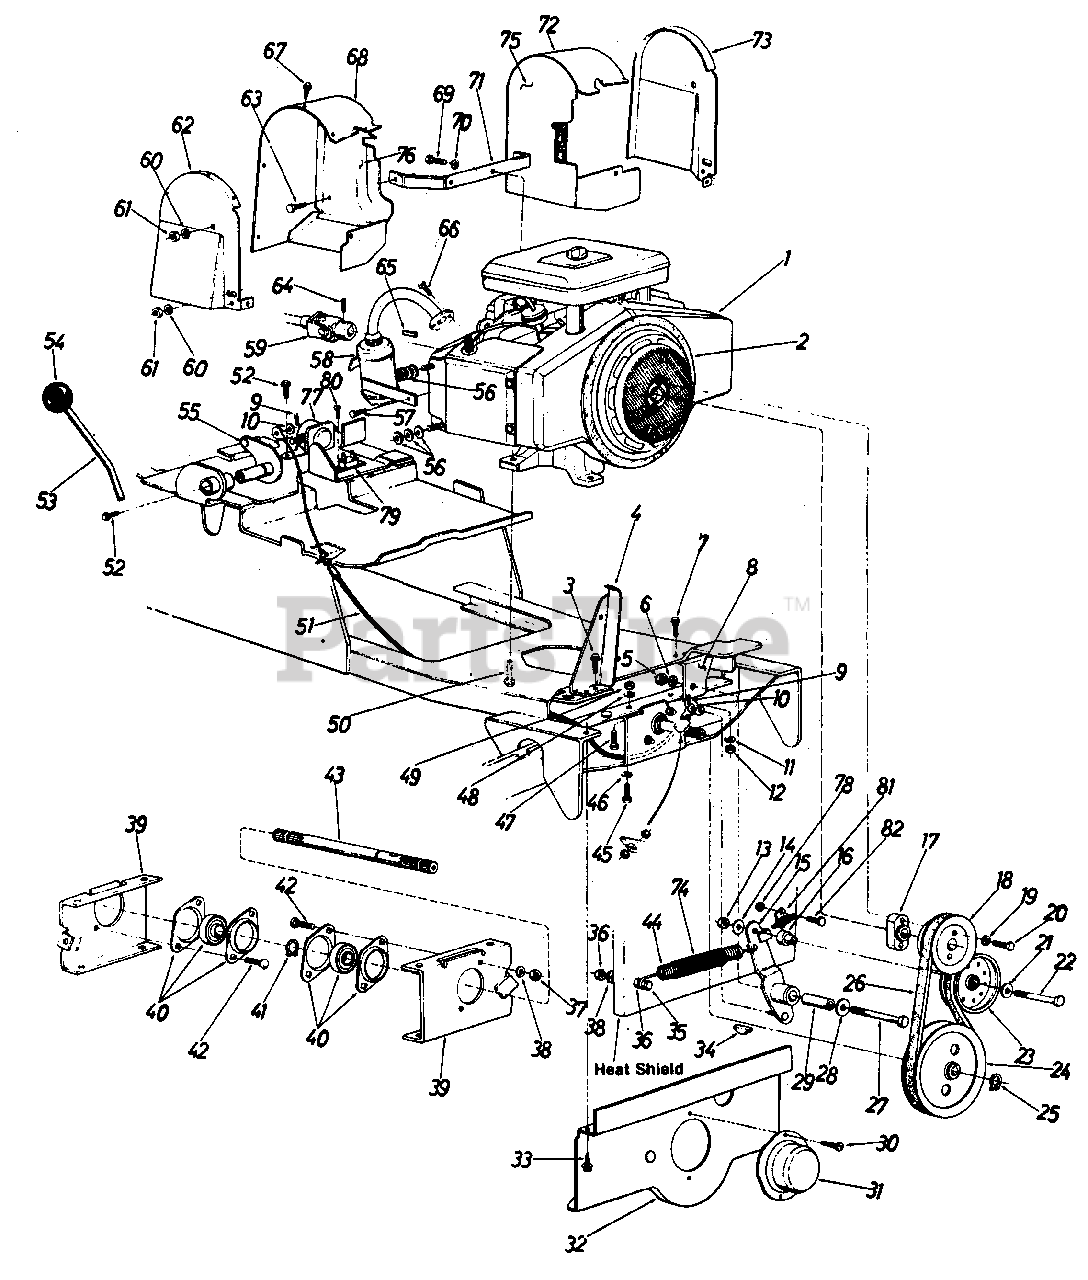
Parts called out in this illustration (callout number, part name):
1	Engine
2	Mylar Foam Strip
3	Hex Wash. Hd. Self-Tap. Scr.1/4-20 X .75" Lg.
6	L-Wash. 3/8" Scr.*
7	Hex Wash. Hd. Self-Tap Scr. 5/16-18 X .75" Lg.
10	Fl-Wash. .38" I.D. x 1.25 O.D. x .10 Thk.
11	L-Wash. 3/8" Scr.*
12	Hex Nut 3/8-16 Thd.*
13	Hex Nut 3/8-16 Thd.*
14	Fl-Wash. .38 I.D. x 1.25" O.D. x .10 Thk.
15	PTO Idler Ass'y.
16	Idler Adapter
17	Pulley Spacer
18	1/2" V-Pulley 4.75" O.D. (Engine)
19	L-Wash. 3/8" Scr. H.D.
20	Hex Scr. 3/8-16 X 2.00" Lg.*
21	Fl-Wash. .38" I.D. x 1.25 O.D. X .010 Thk.
22	Hex Scr. 3/8-16 X 2.50" Lg.*
23	Flat Idler Pulley
24	1/2" V-Puley 7.00" O.D. (PTO)
25	Snap Ring
26	V-Belt 1/2" x 41" Lg. (PTO)
27	Hex Scr. 3/8-16 x 2.50" Lg.*
28	Fl-Wash. .38" I.D. x 1.25" O.D. x .010
29	Spacer .375" I.D. x .62" O.D. x 1.830 Lg.
30	Hex "B" Tap Scr. #10 x .50" Lg.
31	PTO Cup
34	#91 Hi-Pro Key
35	Hex Scr. 5/16-18 X 1.25" Lg.
36	Hex Nut 5/16-18 Thd.*
37	Hex Nut 5/16-18 Thd.*
38	L-Wash. 5/16" Scr.*
39	PTO Brg. Retainer Brkt.
40	1.00" Dia. Brg. w/ Flangette
41	Snap Ring
42	Carr. Bolt 5/16-18 X .75" Lg.*
43	Spline Shaft
44	Extension Spring (PTO Clutch)
45	Hex Scr. 3/8-16 x 1.00" Lg.*
46	L-Wash. 3/8" Scr.*
47	Hex Scr. 3/8-16 x 1.00: Lg.*
48	L-Wash. 3/8" Scr.*
49	Hex Nut 3/8-16 Thd.*
50	Hex Wash. Hd. Self-Tap Scr. 3/8-16 x 1.25" Lg.
51	PTO Control Cable
52	Hex Wash. Hd. Self-Tap Scr. 1/4-20 x .50"
53	PTO Handle
54	Ball Knob
55	PTO Actuator Lever Ass'y.
56	Fl-Wash. .312" I.D. x 1.620" O.D. x .060
57	Hex Wash. Hd. Self-Tap Scr. 1/4-20 x .50" Lg.
58	Muffler Ass'y. Comp.-R.H.
59	Universal Joint Ass'y. Comp.
60	Fl-Wash. .312" I.D. x .630" O.D. x .063
61	Hex Nut 5/16-18 Thd.*
62	Shroud Outer-R.H.
63	Hex Wash. Hd. Self-Tap Scr. 1/4-20 x .50" Lg.
64	Sq. Hd. Set Scr. 5/16-18 x .38" Lg. (Cup Point)
65	Sq. Key 1/4" x 2.00" Lg.
66	Hex Wash. Hd. Scr. 1/4-20 x 5/8" Lg.-Grade 5
67	Hex "AB" Tap Scr. #10 x .50 " Lg.
68	Shroud Cover-R.H.
69	Hex Scr. 5/16-24 X .75" Lg.*
70	L-Wash. 5/16" Scr.
71	Shroud Support Brkt.
72	Shroud Cover-L.H.
73	Shroud Outer-L.H.
74	Spring Cover Tubing (PTO Clutch)
75	Shroud Inner Ass'y.-L.H.
76	Shroud Inner Ass'y.-R.H.
77	Solenoid
78	Hex Scr. 1/4-20 X 1/2" Lg.
79	Circuit Breaker
80	Truss Mach. Scr. #10 x .50" Lg.
81	Safety Switch (PTO)
82	L-Wash. 1/4" Scr.*
